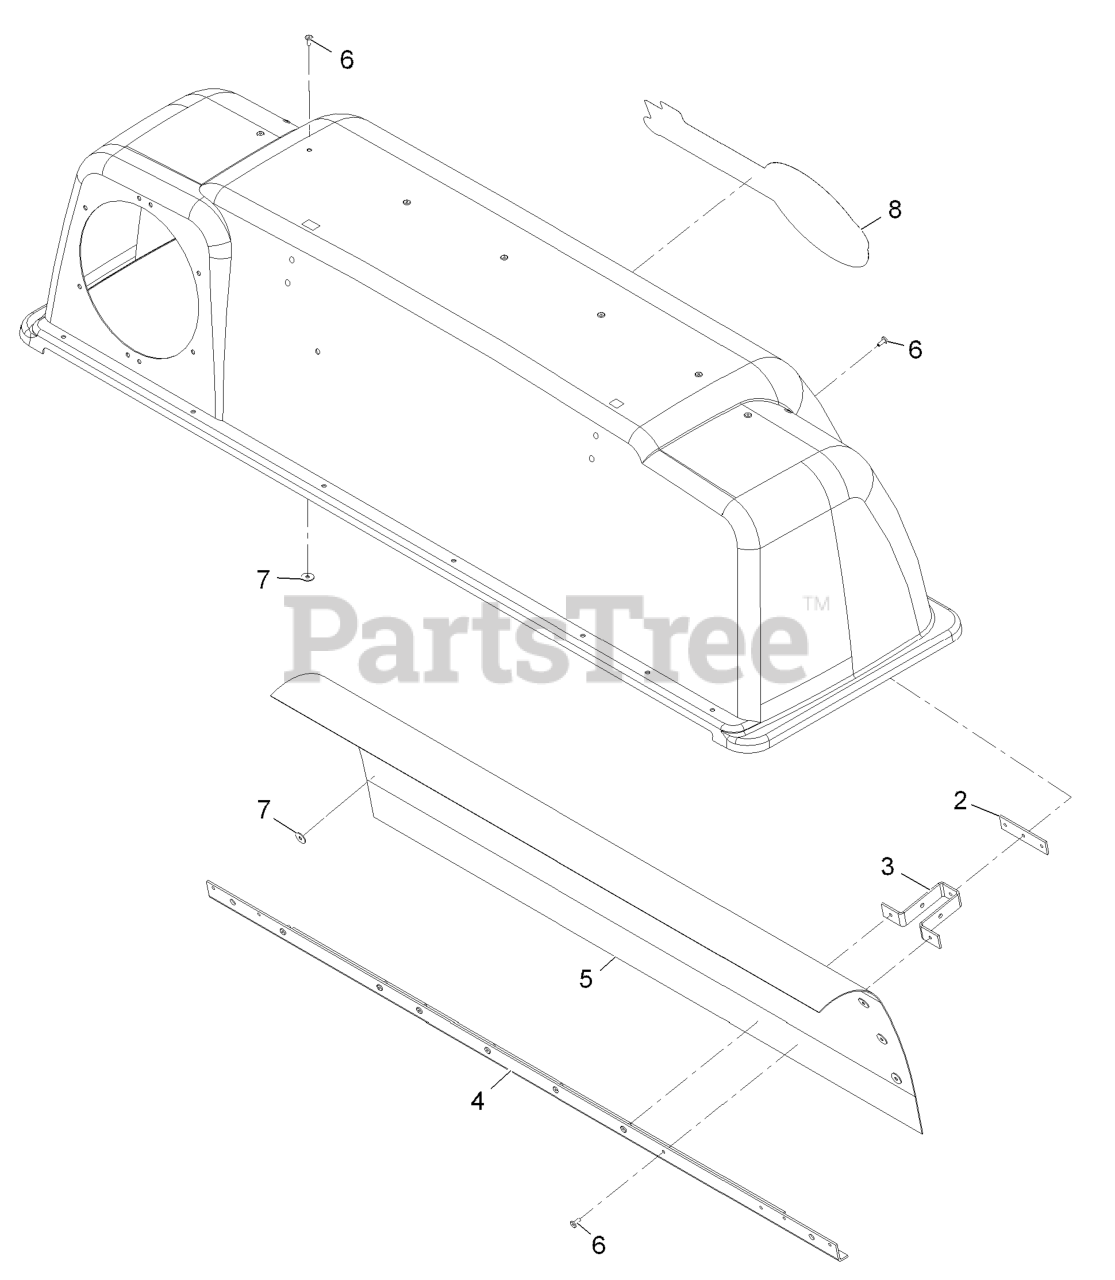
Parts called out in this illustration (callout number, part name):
2	PLATE-LATCH, REINFORCEMEN
3	BRACKET-MOUNT
4	SUPPORT-SCREEN
5	SCREEN-BAGGER
6	RIVET-BLIND
7	WASHER-FLAT
8	DECAL, EXMARK
